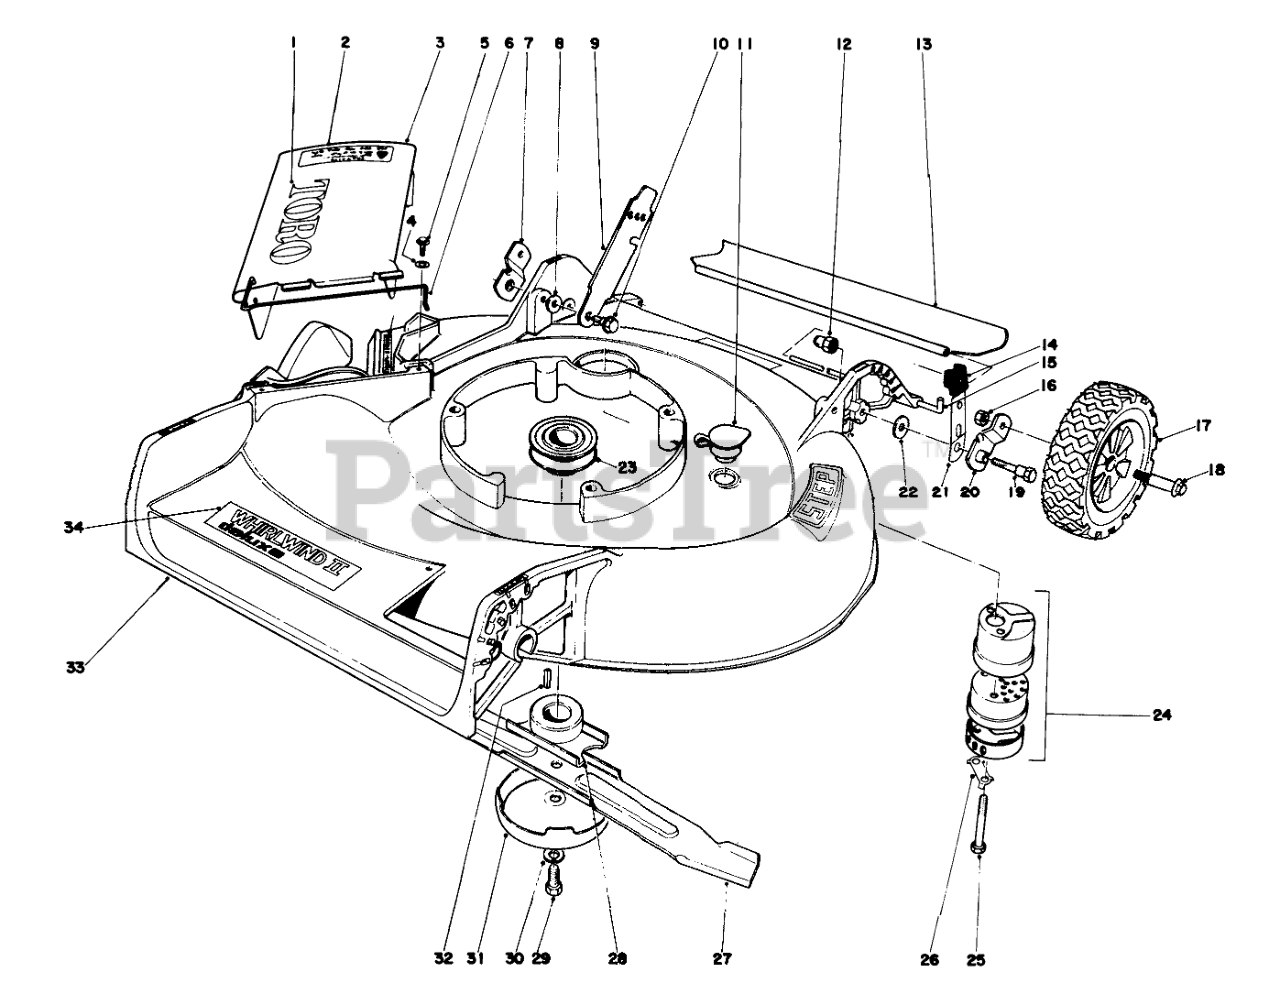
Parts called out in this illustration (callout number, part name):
1	TORO LOGO DECAL
2	Caution Decal
3	Deflector Cover Assembly (Incl. Ref. #1-2 & 6)
4	WASHER-FLAT
5	SCREW
6	SPRING HINGE
7	Pivot Arm
8	SPACER
9	Latch
10	SCREW-SHOULDER
11	WASHOUT PLUG
12	HANDLE PIVOT NUT
13	REAR SAFETY SHIELD 21
14	KNOB-ARM
15	SHIELD ROD
16	Nut
17	WHEEL TIRE ASM 8 IN
18	BOLT-WHEEL
19	5/16-18 PIVOT SCREW
20	Pivot Arm
21	SPRING ARM ASM
22	WASHER-PIVOT
23	DRIVER PULLEY
24	Muffler Assembly (Incl. Ref. #25 & 26)
25	SCREW-HH
26	CLIP - LOCKING
27	Blade
28	Blade Retailer
29	SPECIAL SCREW
30	WASHER-LOCK
31	AntiScalp Cup
32	KEY-SQUARE
33	Housing
34	Decal Deck
35	Decal
